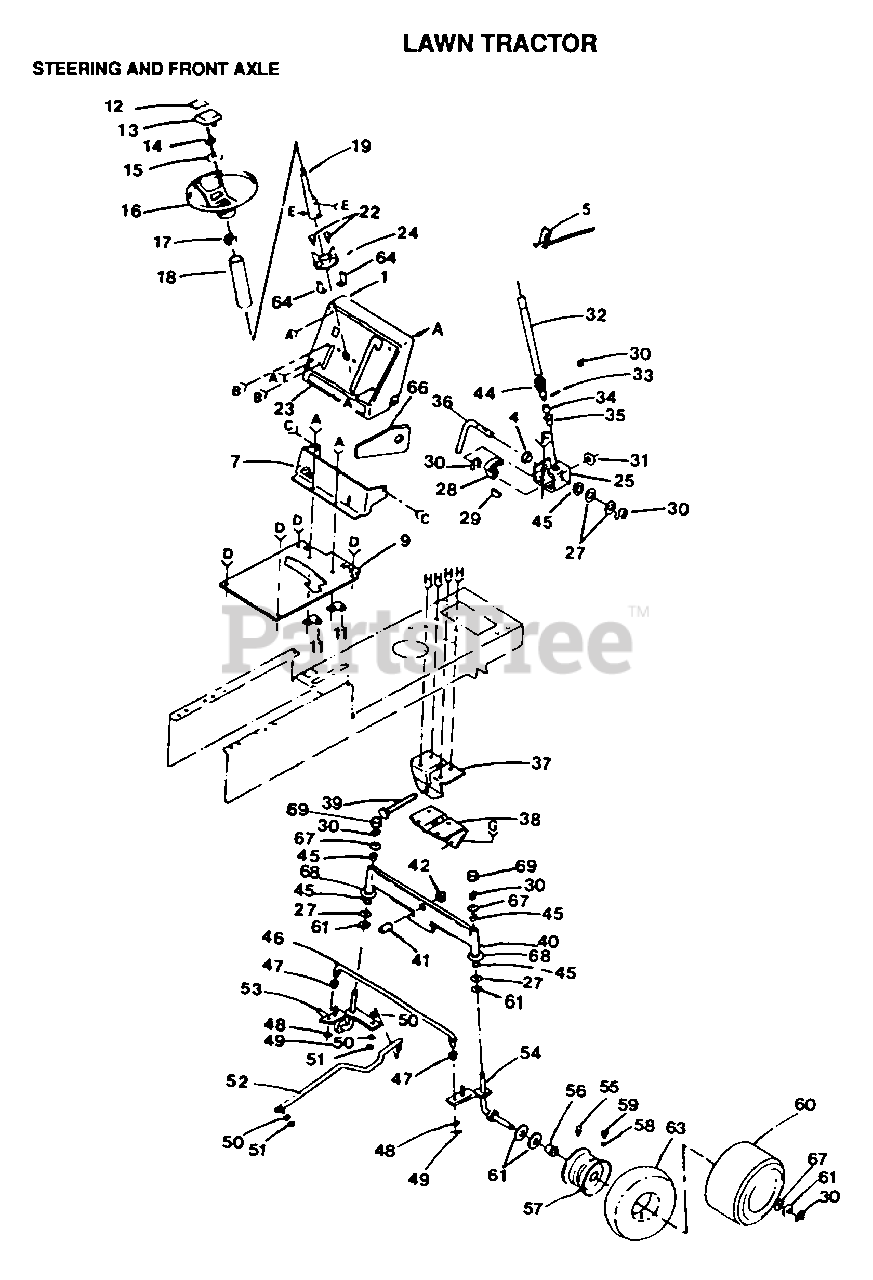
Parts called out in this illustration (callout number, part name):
4	NYLINER T
7	DASH-LOWER LT
11	CLIP T
13	INSERT-WHEEL LT
15	WASHER
17	ADAPTER LT
19	STEERING SHAFT
24	BUSHING T
27	WASHER .T
28	GEAR.SECTOR.HYT
29	KEY-WOODRUFF LT
30	RING
32	STEERING SHAFT T
34	SHAFT SPACER LT
35	BUSHING
36	ROD STEERING T
37	SUPPORT-SADDL T
38	SUPPORT.SADDLE.FT
39	BOLT LT
41	BEARING
42	"NUT-LOC,FLANGE LT"
44	GEAR PINION T
45	COL. SRTG. BEAR.
48	WASHER
49	COTTER PIN
50	LOCKWASHER
52	LINK-DRAG LT
53	SPINDLE-LH LT
55	FITTING LT
56	"FLANGE, BEARING"
58	VALVE CAP
59	VALVE STEM LT
61	WASHER
63	TUBE.5.3/4.5/6
64	RETAINER T
67	WASHER
68	WASHER
69	CAP
